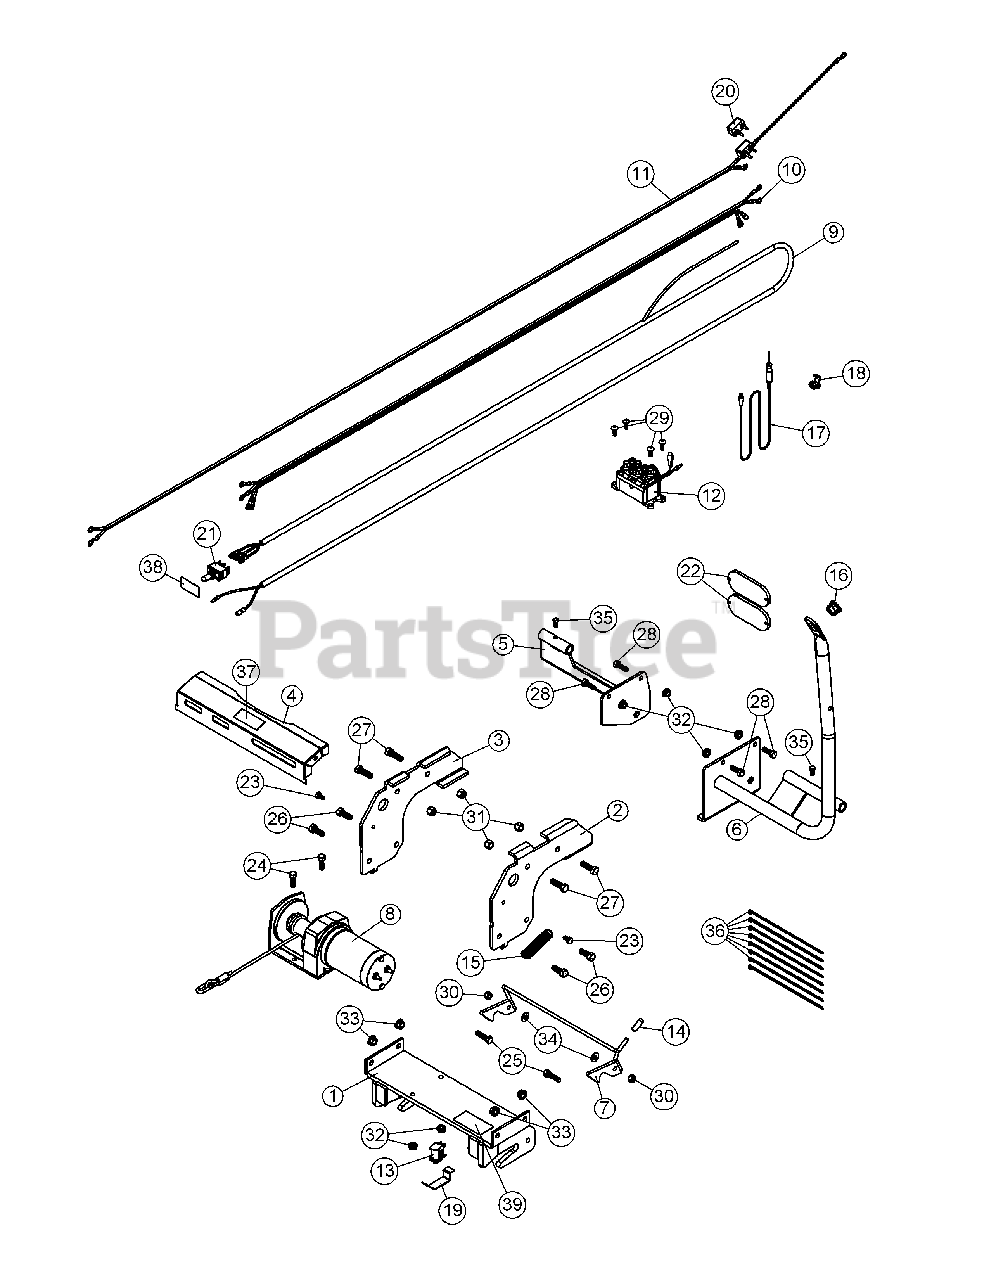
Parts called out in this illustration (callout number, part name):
1	Female hitch
2	Left support
3	Right support
4	Heat shield
5	Cab support
6	Handle support
8	Winch assembly
9	Winch control wire
10	Wire assembly
11	Wire assembly
13	Limit switch
16	Plastic grommet
17	Hi/low voltage tester
18	Instant connector
19	Push plate
21	Winch control switch
22	Reflector (Pack of 2)
23	Hex. bolt 1/4" n.c. x 1/2" GR5
24	Hex. bolt 5/16" n.c. x 1" GR5
25	Hex. bolt 5/16" n.c. x 1 1/4" GR5
26	Hex. bolt 3/8" n.c. x 1" GR5
27	Hex. bolt 3/8" n.c. x 1 1/4" GR5
28	Thread cutting screw 5/16" n.c. x 1"
29	Metal screw T.H. #12" x 3/4"
30	Nylon Insert lock Nut 5/16" n.c. GR5
31	Nylon Insert lock Nut 3/8" n.c.
32	Flange nut 5/16" n.c.
33	Flange nut 3/8" n.c.
34	Flat washer 5/16" hole
35	Square head set screw 5/16" x 1/2"
36	Tie wrap 8"
37	Decal caution hot surfaces
38	Lift decal
